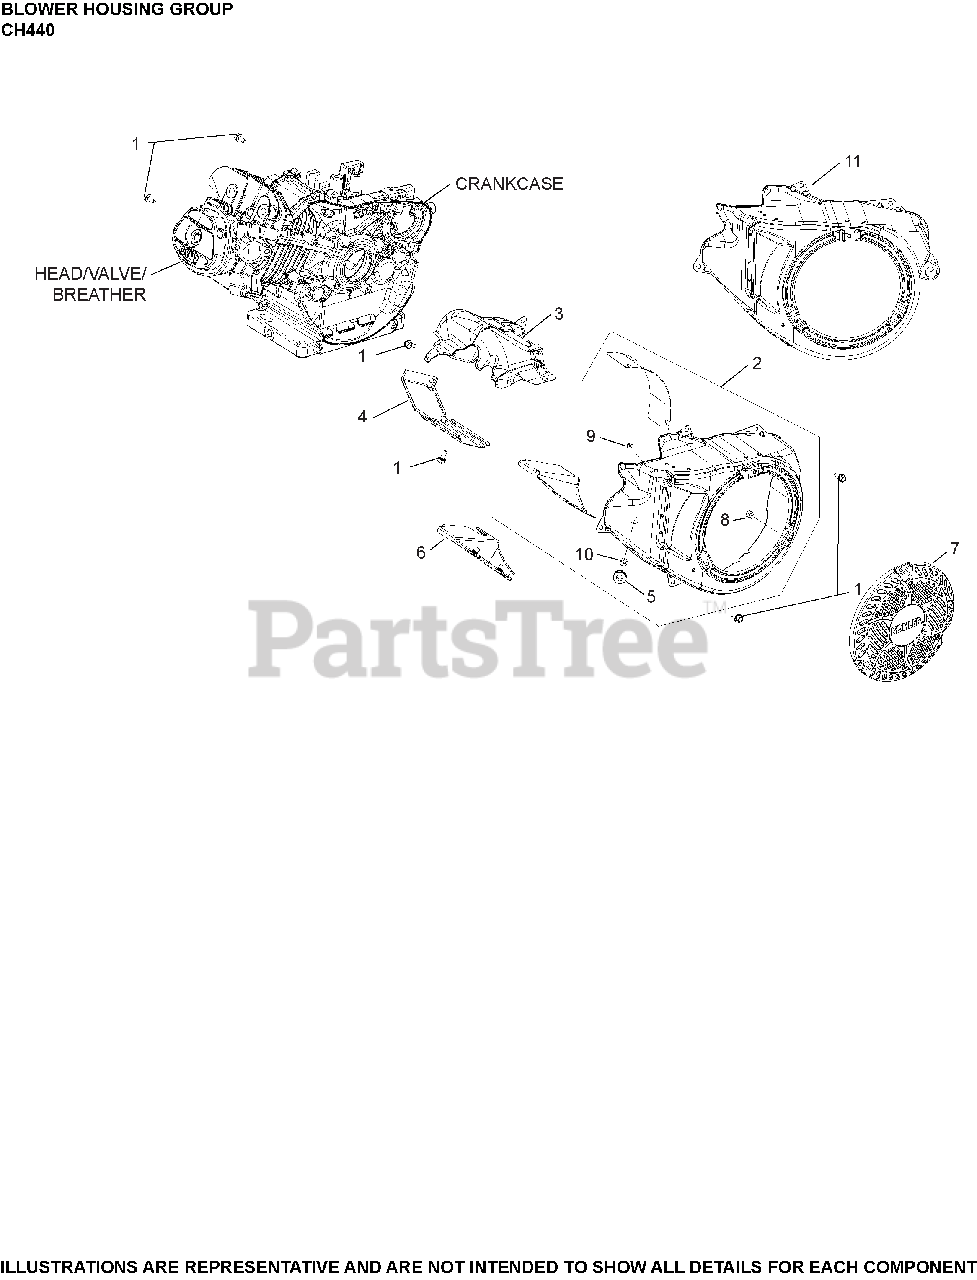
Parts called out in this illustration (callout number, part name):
1	SCREW, HEX FLANGE (M6)-USE 25 086 433-S
2	HOUSING, BLOWER ASSEMBLY
3	SHIELD, UPPER HEAT
4	SHIELD, CYLINDER HEAD
5	ISOLATOR, VIBRATION
6	NUT, BLOWER HOUSING (CKY)
7	NUT, BLOWER HOUSING (CKY)
